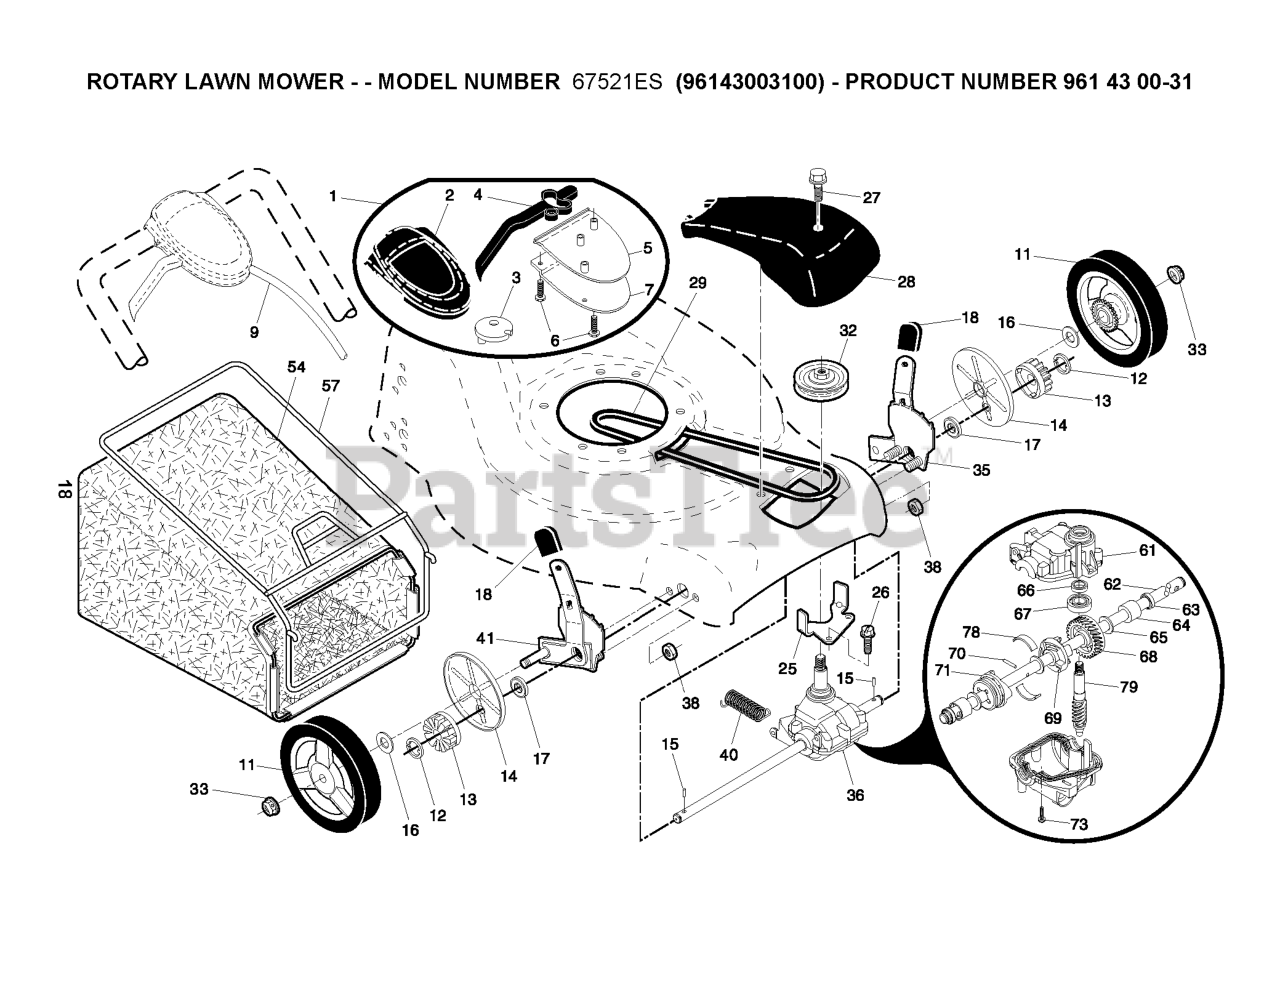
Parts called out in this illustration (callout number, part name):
1	DRIVE CONTROL ASSEMBLY (INCLUD
2	COVER TOP AUTO WALK CONTROL
3	PULLEY
4	LEVER, AUTOWALK DRIVE CONTROL
5	COVER BOTTOM AUTO WLK CONTROL
6	SCREW, PHILLIPS HEAD 10 X 5/8
7	BRACKET.DRIVE.CONTROL.MOUNT.BL
9	CABLE ASSEMBLY, DRIVE
11	WHEEL.8X1.75.H3SPK.RAD3.GY.BU3
12	E-RING 7/16 RE
13	PINION.14.TEETH.FGD
14	COVER.DUST.WHEEL
15	PAWL, DRIVE
16	WASHER FLUT
17	BEARING
18	KNOB.DELUXE.GRAY
25	BELT KEEPER
27	SCREW, HEX HD TAPPING #10-24 1
28	COVER.DR.21.FWGD/B&S.GRAY
29	BELT.DRIVE.FG
32	RP PULLEY.DRIVE.EZ
33	NUT.HEX.FLANGE.3/8-16.LO(3 2)
35	WHEEL ADJ KIT LH
36	TRANSMISSION.21.FGD.HT.VST
38	LOCKNUT.NYLOC.1/4-20
41	WHEEL ADJ KIT RH
54	GBAG.34710247.SILVER.H
57	FRAME.GBAG.21.FWGD
61	CASE.UPPER.00254(SERVICE)
62	SHAFT OUTPUT (12289)
63	SEAL.OUTPUT.SHAFT
66	SEAL INPUT SHAFT
68	GEAR 28 TEETH 36208
69	FIXED DOG CLUTCH
70	PIN.3.50.33733
71	MOVEABLE DOG CLUTCH
78	SPRING LEAF
79	SHAFT WORM
